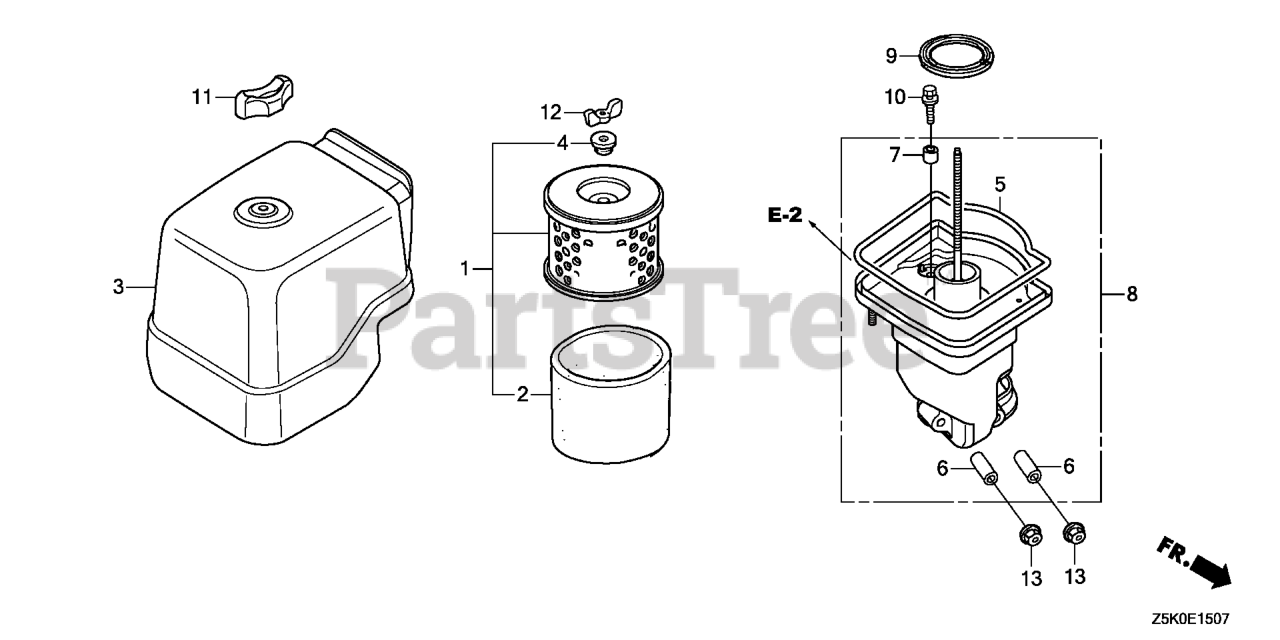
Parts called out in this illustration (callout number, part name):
1	ELEMENT, AIR CLEANER
2	FILTER (OUTER)
3	COVER ASSY., AIR CLEANER (CYCLONE)
4	GROMMET, AIR CLEANER
5	SEAL, AIR CLEANER COVER
6	COLLAR, AIR CLEANER
7	COLLAR B, AIR CLEANER
8	ELBOW, AIR CLEANER
9	GASKET, AIR CLEANER HOUSING
10	BOLT-WASHER (6X22)
11	NUT, AIR CLEANER
12	WINGNUT, TOOL BOX SETTING
13	NUT, FLANGE (6MM)
